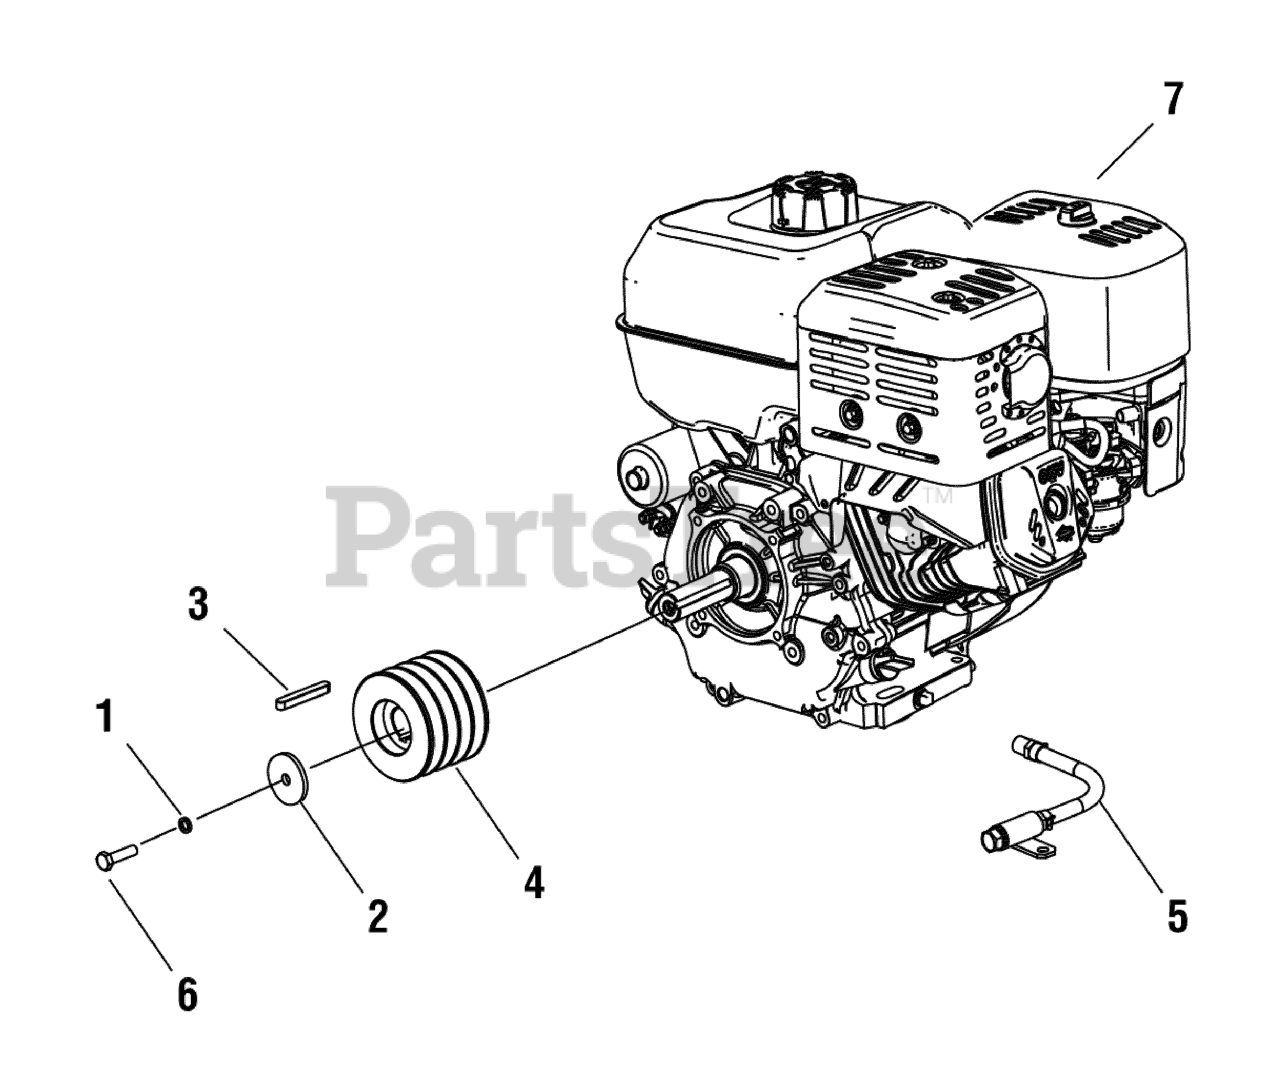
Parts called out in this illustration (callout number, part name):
1	WASHER, Spring, 8
2	WASHER, Flat
4	PULLEY, Engine
5	EXHAUST OIL ASSEMBLY
6	BOLT, Hex, M8 x 30
7	ENGINE, 420CC
